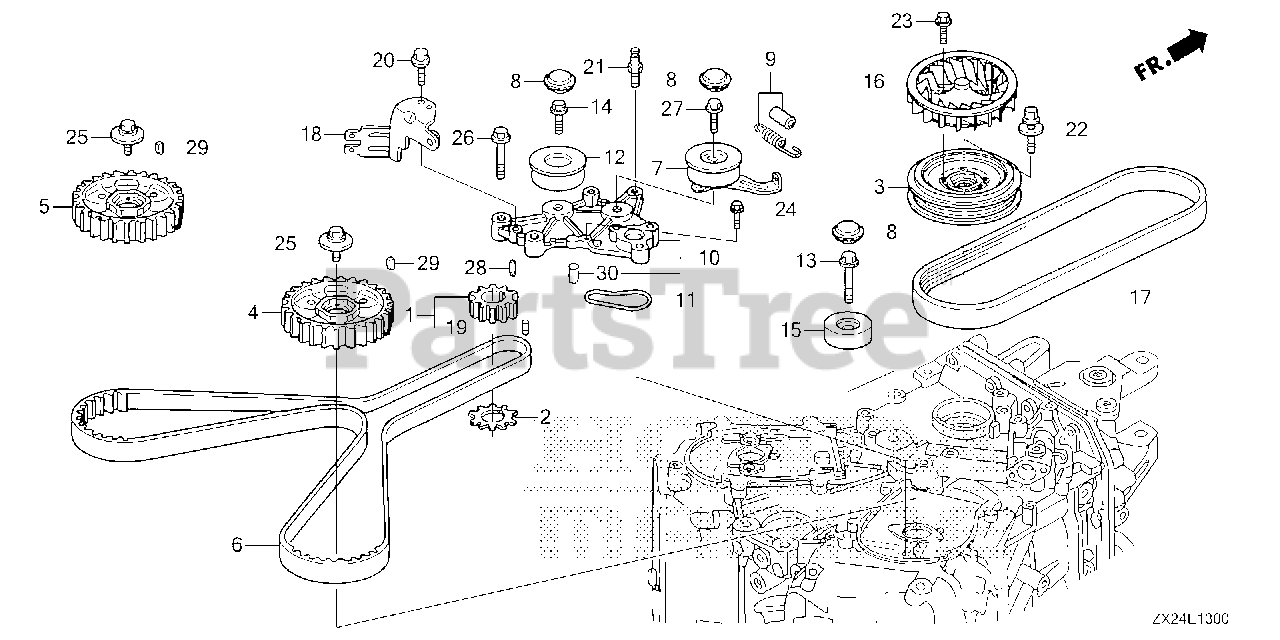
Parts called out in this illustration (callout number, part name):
1	PULLEY, TIMING BELT DRIVE
2	PLATE, TIMING BELT GUIDE
3	PULLEY, CRANKSHAFT
4	PULLEY, R. TIMING BELT DRIVEN
5	PULLEY, L. TIMING BELT DRIVEN
6	BELT, TIMING (197YU26 GB-323)
7	TENSIONER, TIMING BELT
8	CAP, TIMING BELT TENSIONER
9	SPRING, TIMING BELT ADJUSTING
10	BASE, TIMING BELT TENSIONER *NH8* (DARK GRAY)
11	O-RING, TIMING BELT TENSIONER BASE
12	IDLER, TIMING BELT (KOYO SEIKO)
13	BOLT, IDLER
14	BOLT, TIMING BELT IDLER A
15	IDLER B, TIMING BELT
16	FAN, COOLING
17	BELT, ALTERNATOR (6PK745 M-180)
18	BRACKET, CONNECTOR D
19	PIN, VERTICAL SHAFT
20	BOLT, FLANGE (6X14) (CT200)
21	BOLT, TIMING BELT ADJUSTING SPRING
22	BOLT-WASHER (16X49)
23	BOLT, FLANGE (6X16)
24	BOLT, FLANGE (6X22)
25	BOLT-WASHER (12X35)
26	BOLT, FLANGE (10X40)
27	BOLT, FLANGE (10X43)
28	KEY (4.5X24)
29	KEY, SPECIAL
30	PIN, DOWEL (6X10)
